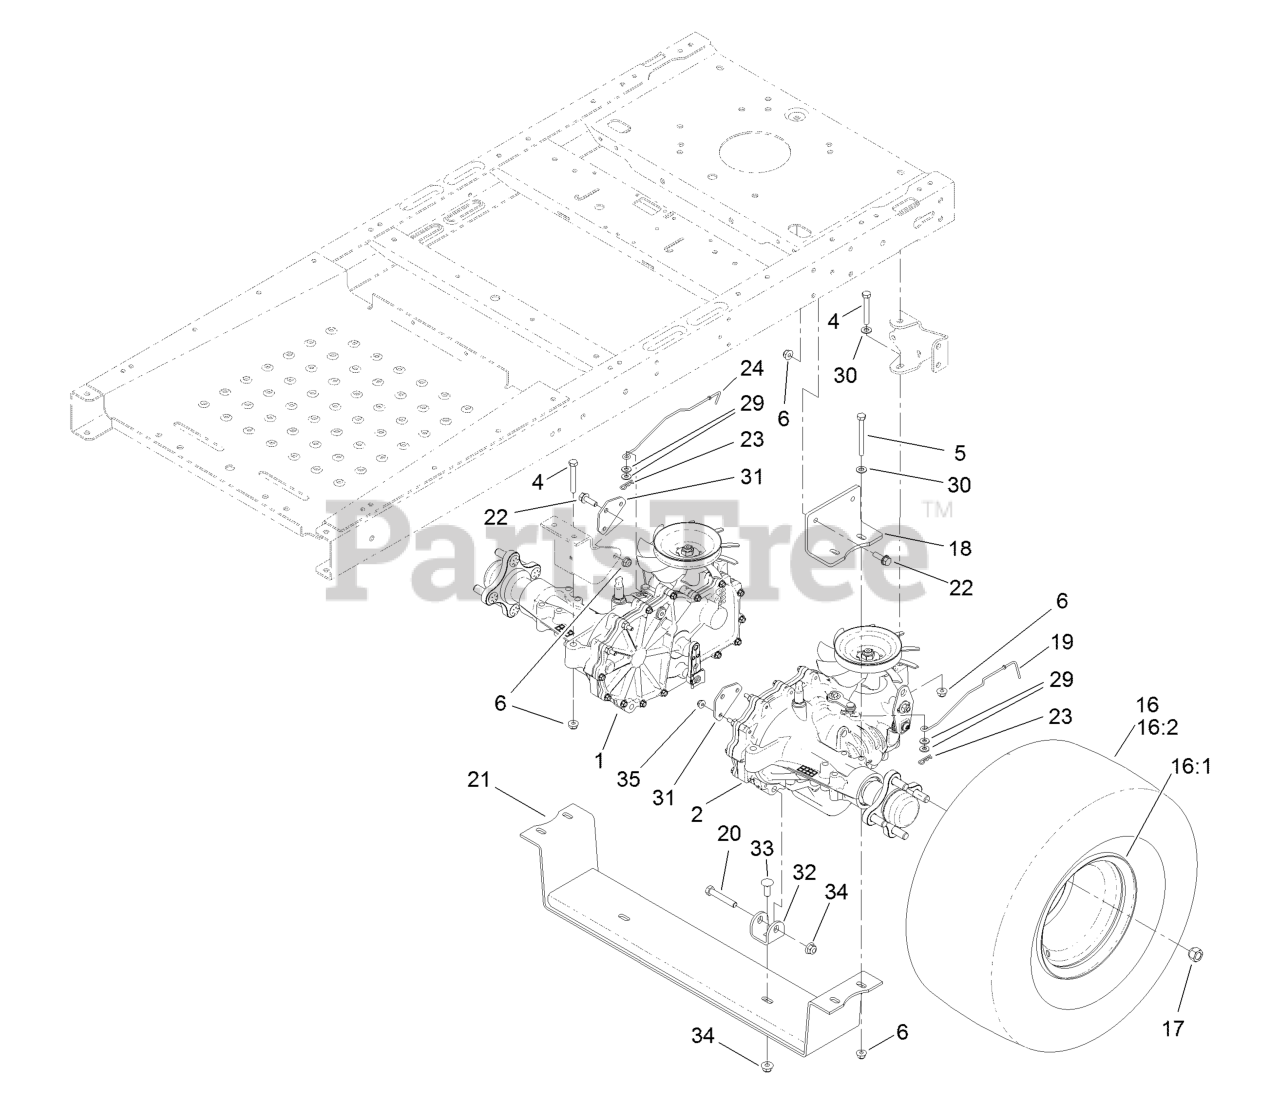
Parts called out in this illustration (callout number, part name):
1	RH HYDRO TRANSAXLE ASM
2	LH HYDRO TRANSAXLE ASM
4	SCREW-HH
5	SCREW-HH
6	NUT-HF, NI
16	WHEEL AND TIRE ASM
16:1	WHEEL,10 X 6.00
17	NUT-LUG
18	MOUNT-HYDRO
19	ROD-BYPASS, LH
20	SCREW-HH
21	MOUNT-HYDRO
22	SCREW-HHF
24	ROD-BYPASS, RH
29	WASHER-FLAT
30	WASHER-PLAIN
31	PLATE-HYDRO MOUNT
32	TAB-HYDRO
33	BOLT-CARR
34	NUT-HF, NI
